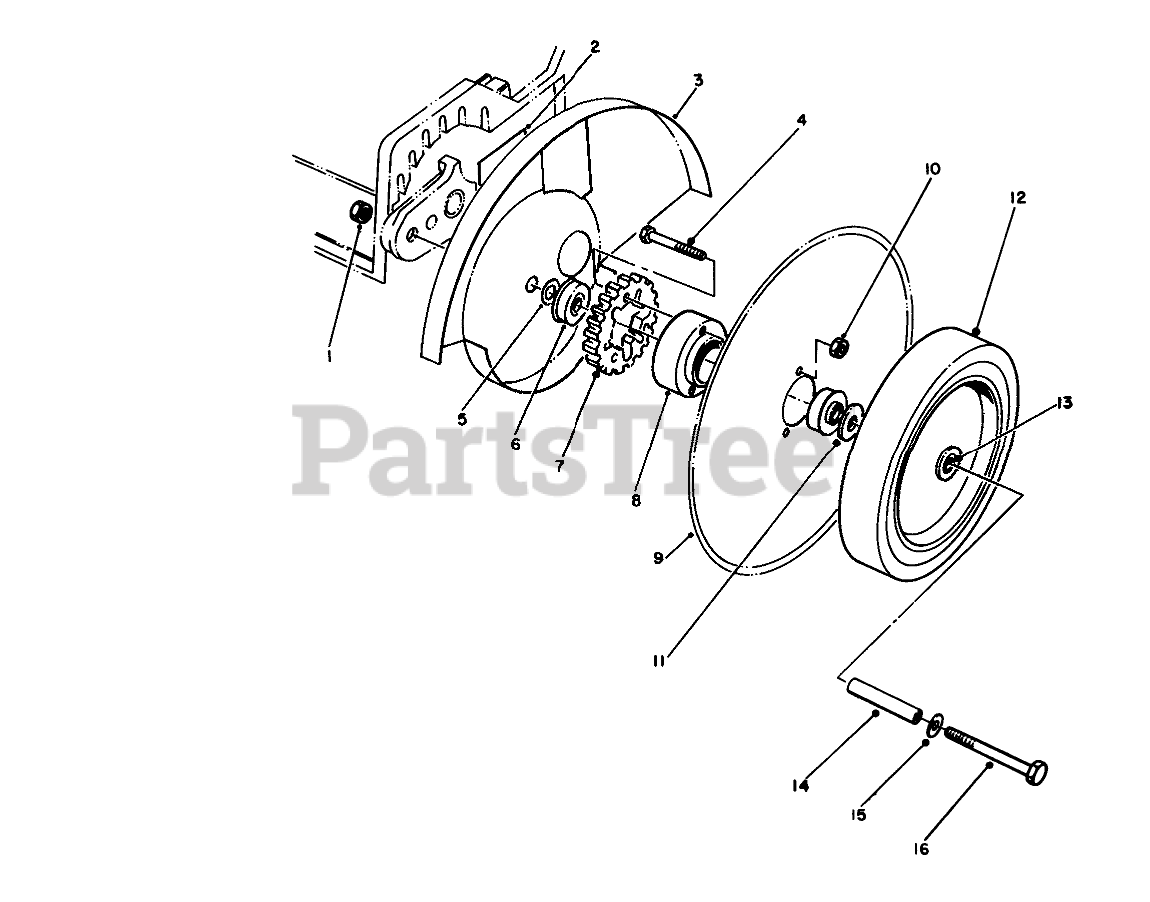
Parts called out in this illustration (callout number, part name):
1	Nut
2	Decal-Toro Edger
3	Shield
4	SCREW-HH
5	WASHER
6	BEARING-BALL
7	Gear-Wheel
8	Spacer-Hub
9	Blade-Edger 80 Tooth
10	NUT-LOCK, SIDE
11	WASHER
12	Wheel Assy. (Incl. Ref. #13)
13	BUSHING
14	Spacer-Wheel Bolt
15	WASHER-FLAT
16	SCREW-HH
